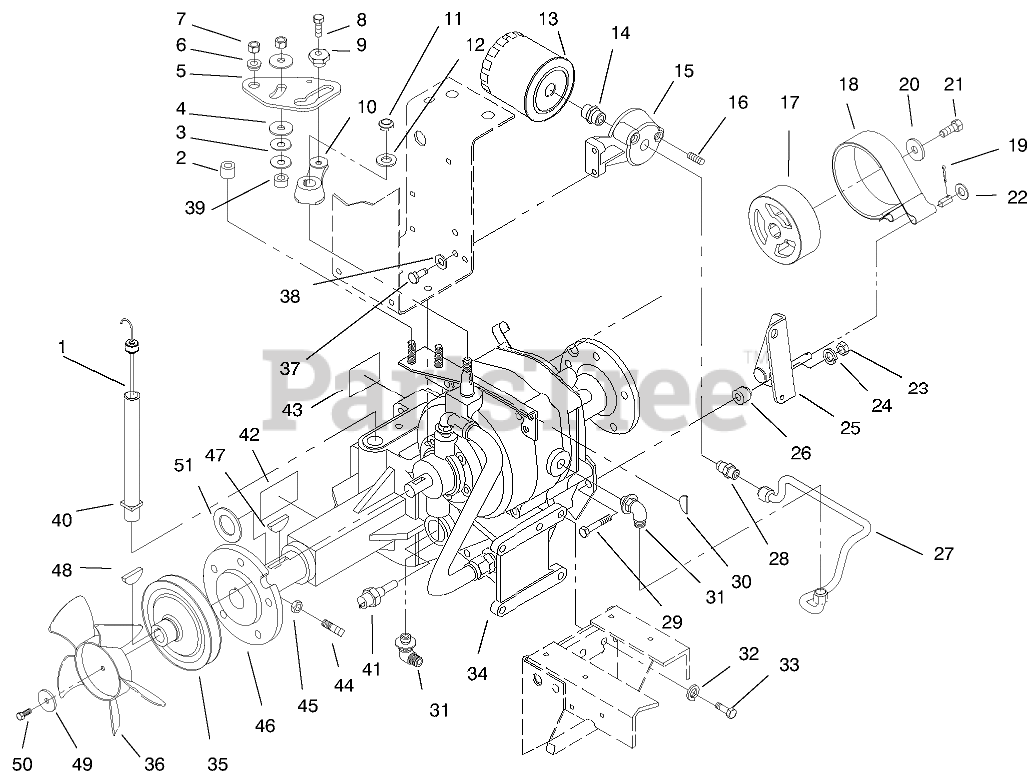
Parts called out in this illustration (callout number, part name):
1	ASSY DIPSTICK (BLACK)
2	SPACER-PIVOT
3	WASHER-SPRING DISC
4	FRICTION WASHER
5	CAM-SPEED CONTROL (NS)
6	CAM-SPACER
8	Screw-HH
10	Arm-Speed Control
11	NUT-LOCK, NI
12	WASHER-FLAT
13	OIL FILTER ASM
14	FITTING
15	BASE-FILTER
17	DRUM-BRAKE
18	ASSY-BRAKE BAND
19	PIN-COTTER
20	WASHER
21	SCREW-HH, LOCK
22	WASHER-FLAT
23	NUT-LOCK, NI
24	WASHER-FLAT
25	Pivot Arm-Brake
26	BUSHING-BRAKE PIVOT
27	ASS'Y-TUBE FILTER
28	FITTING
29	SCREW-HH
30	KEY-WOODRUFF
31	ELBOW
32	WASHER-LOCK
33	SCREW-HH
34	Transaxle/Decal(Servi e)
35	PULLEY
36	NYLON FAN-L-CW
37	SCREW-HH
38	WASHER-LOCK
39	SPACER-FRICTION
40	NIPPLE-TRANS FILL
41	SENSOR-HYDRO OIL HOT
42	DECAL - DANGER
43	DECAL-UNIDRIVE
44	SCREW-SET, SQH
45	NUT-JAM
46	HUB-WHEEL
47	KEY-WOODRUFF
48	KEY-WOODRUFF
49	WASHER
50	SCREW-HEX HD CAP
51	WASHER-THRUST
